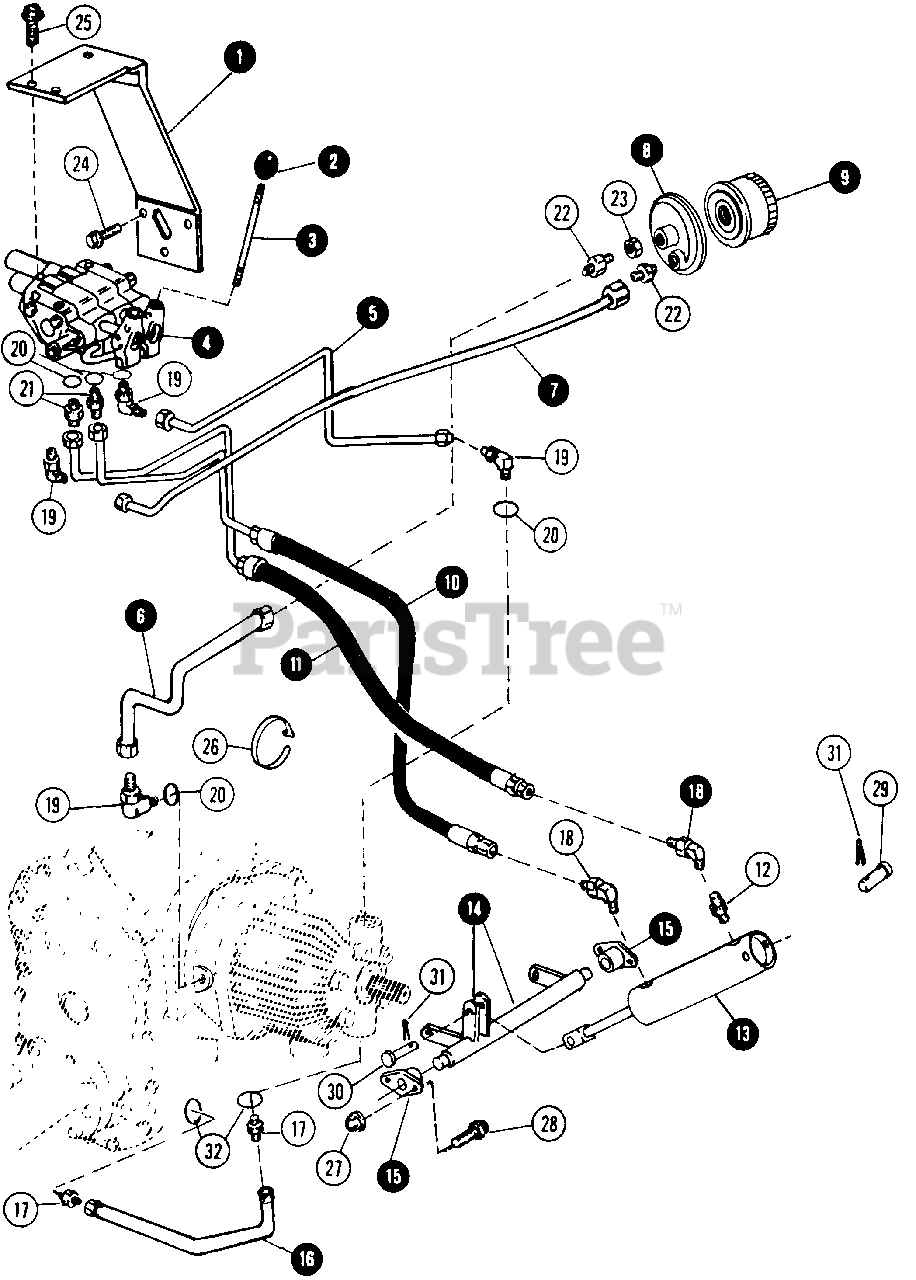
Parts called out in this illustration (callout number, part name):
1	BRACKET, VALVE SUPPORT
2	KNOB, CONTROL HANDLE
3	HANDLE, VALVE CONTROL
4	VALVE, 2-SPOOL
5	TUBE, CHARGE PUMP TO VALVE
6	TUBE, FILTER TO TRANSMISSION
7	TUBE, VALVE TO FILTER
8	BASE, OIL FILTER
9	FILTER, HYDRAULIC OIL
10	HOSE-TUBE, VALVE TO CYLINDER - ROD END
11	HOSE-TUBE, VALVE TO CYLINDER - HEAD END
12	CONNECTOR, 1/4P.T. x 9/16-18 STRAIGHT THREAD
13	CYLINDER, MID-MOUNT LIFT
14	SHAFT, LIFT
15	BEARING, LIFT SHAFT
16	TUBE, TRANSAXLE TO TRANSMISSION
17	CONNECTOR, 7/8-14 STRAIGHT THREAD
18	ELBOW, 90 DEGREE 1/4P.T. x 9/16-18 STRAIGHT THREAD
19	ELBOW, 90 DEGREE 9/16-18 STRAIGHT HEAD
20	O-RING, 906 (.08 x .47 I.D.)
21	CONNECTOR, 9/16-18 STRAIGHT THREAD
22	CONNECTOR
23	NUT, 3/4 HALF HEX
24	BOLT, 3/8C x 7/8 HEX FLANGE LOCK
25	BOLT, 5/16C x 1 HEX FLANGE LOCK
26	STRAP, HOSE RETAINER
27	NUT, 3/8C x 1 HEX FLANGE LOCK
28	BOLT, 3/8C x 1 HEX FLANGE LOCK
29	CLEVIS-PIN, 1/2 x 3-7/16
30	CLEVIS-PIN, 1/2 x 1-7/8
31	COTTER-PIN, 1/8 x 1"
32	O-RING, 910 (.10 x .75 I.D.)
